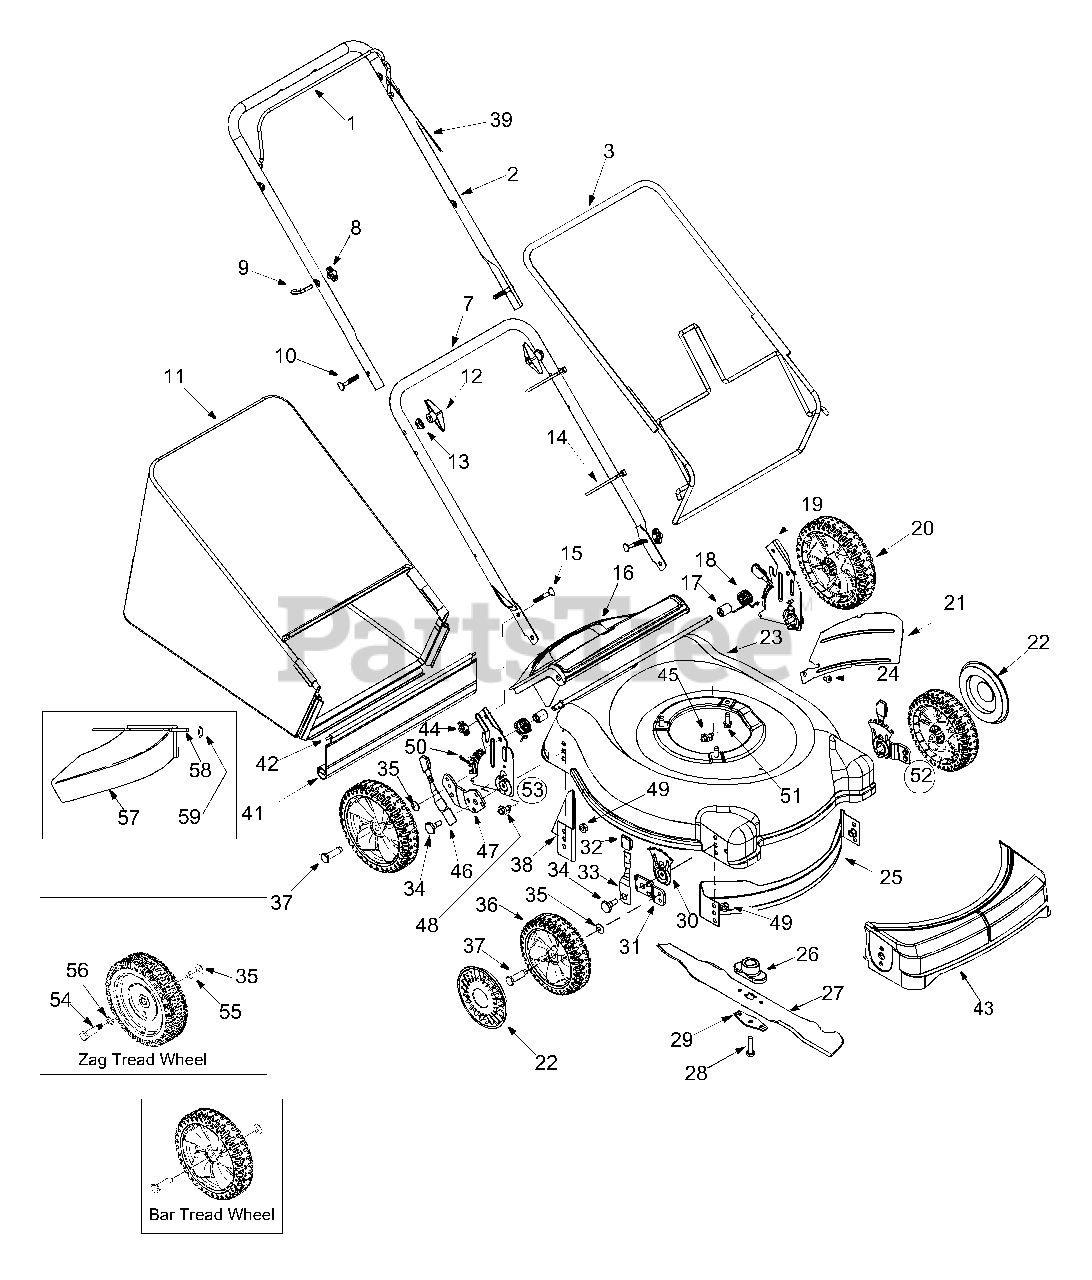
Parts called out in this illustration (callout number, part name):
8	Wing Nut
9	Rope Guide
10	Carriage Bolt 5/16-18 x 2
11	Grass Bag Assembly
12	Hand Knob
13	Saddle Washer
14	Cable Tie
15	Carriage Bolt 1/4-20
16	Rear Discharge Door
17	Spacer
18	Torsion Spring LH
22	Hubcap
24	AB Screw 1/4-14 x .625"
27	Mulching Blade
28	Hex Bolt 3/8-24 x 1.5
29	Blade Bell Support
30	Front Adjustment Plate
32	Knob: Adjustment Lever
33	Spring Lever Assembly
34	Shoulder Screw
35	Bell Washer .375 x .870
36	Front Wheel
37	Shoulder Screw .498 x 1.4
39	Control Cable 37.25"
41	Trail shield
42	Trail shield Wire
43	Deck: Front Cover
44	Wing Nut 1/4-20
45	Hex L-Washer Hd. Screw 3/8-16 x 1.0
46	Lever Assembly: Rear Height Adj.
47	Pivot Bar: 9 Position RH
48	AB Screw 1/4-14 x .625
49	Flange Lock Nut 3/8-16
50	Hairpin Clip
51	TT Sems Screw 3/8-16 x 1.0
52	Handle Bracket Assy. Front LH
53	Handle Bracket Assy. Rear LH
54	Rear Axle Bolt
55	Spacer
56	Wave Washer
57	Chute Deflector
58	Rod
59	Push Speed Nut
